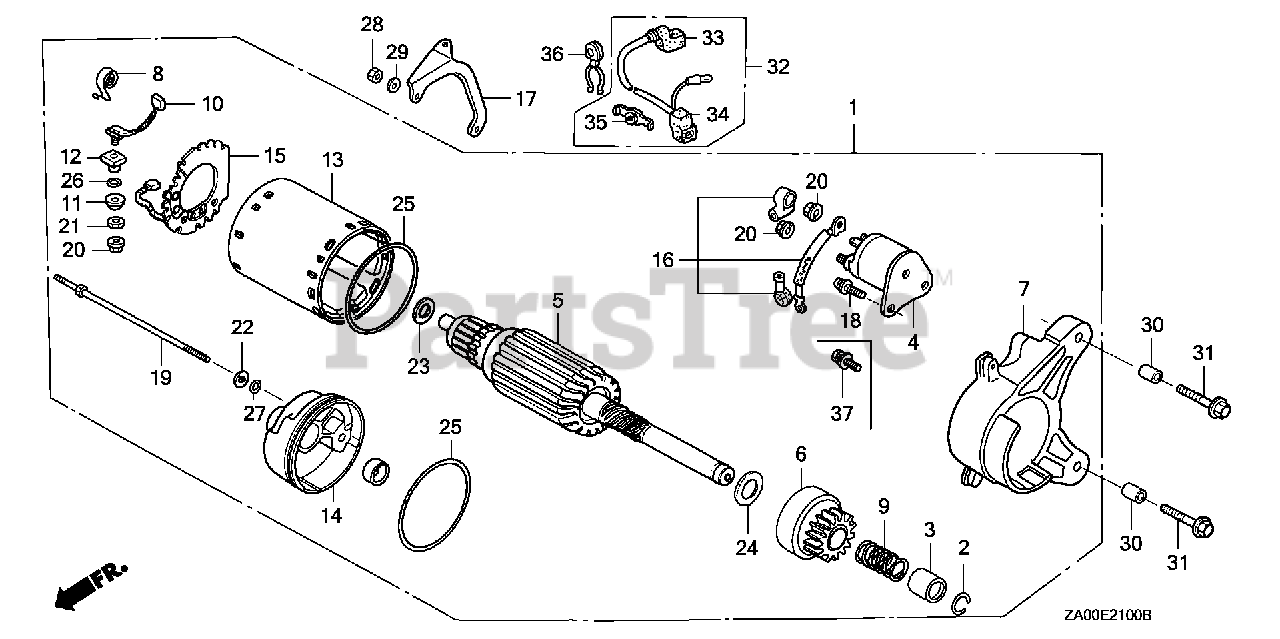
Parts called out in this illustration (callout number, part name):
1	MOTOR ASSY., STARTER
2	RING, SNAP
3	COLLAR, CLUTCH
4	CONTACTOR ASSY.
5	ARMATURE
6	CLUTCH, OVERRUNNING
7	HOUSING, DRIVE SIDE
8	SPRING, BRUSH
9	SPRING
10	BRUSH
11	BUSHING, INSULATION
12	BUSHING, INSULATION
13	YOKE
14	FRAME, STARTER END
15	PLATE, BRUSH HOLDER
16	WIRE, WATER COVER
17	STAY, STARTER MOTOR
18	SCREW-WASHER (5X14)
19	BOLT, THROUGH
20	NUT
21	NUT
23	WASHER
24	WASHER
26	O-RING
27	O-RING
28	NUT, FLANGE (5MM)
29	WASHER, PLAIN (5MM)
30	PIN A, DOWEL (10X16)
31	BOLT, FLANGE (8X40)
